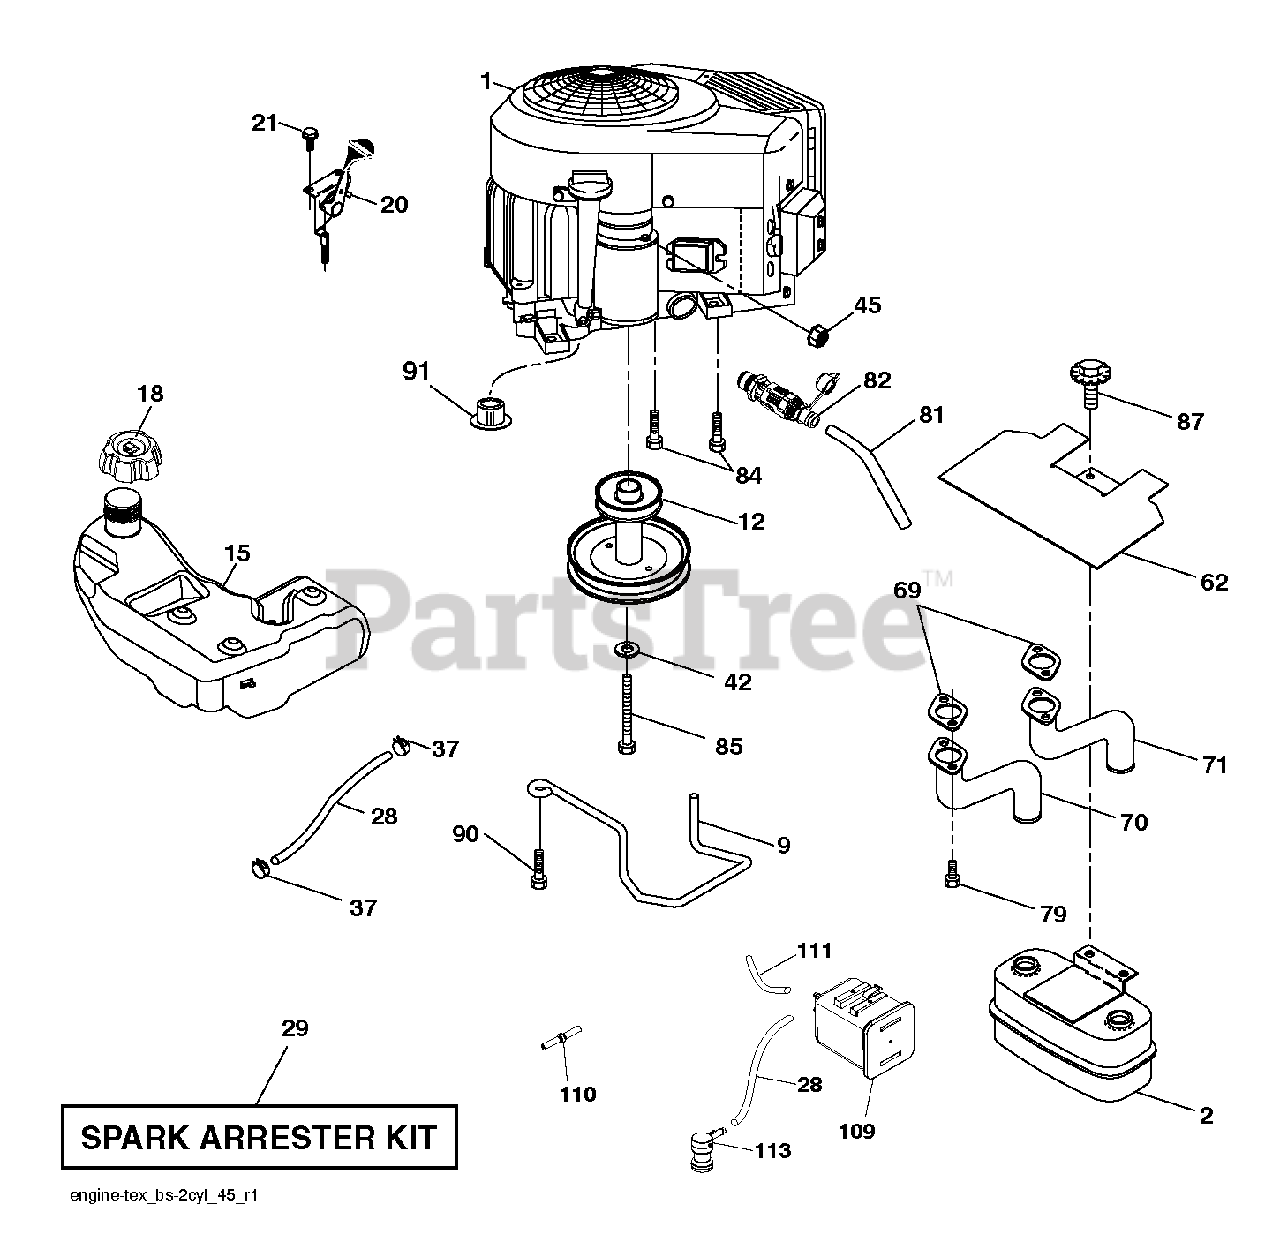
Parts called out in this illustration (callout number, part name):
2	MUFFLER.ASM.TWN.EXTNDED.DFLCTR
9	KEEPER BELT ENGINE
12	PULLY ENGINE
15	TANK ASM.FUEL.3
18	CAP.ASM.FL.RITCH.3"E10.SYM.498
20	CONTROL.TH/CK.COBRA.B&S.TWN.
21	SCREW.#10 X 0.750.BOS
28	LINE.FUEL.64"REAR.EMIS
29	KIT.SPARK ARRESTOR 794945 B&S
37	HOSE CLAMP
42	LOCKWASHER
45	NUT
62	SHIELD.HEAT.MUFFLER
69	GASKET.MUFFLER
70	EXHAUST.TUBE.LH.BS/TWIN
71	EXHAUST.TUBE.RH.B&S.TWIN.INTEK
79	SCREW.SOCKET.HEAD.5/16-18
81	TUBE, DRAIN OIL ASM.
82	VALUE.OIL.DRAIN
84	SCREW.3/8-16
85	BOLT HEX 7/16-20X4-1/4"
87	BOLT, 5/16-18 X 1 3/4
90	SCREW 3/8-16X1
91	BUSHING.1.375OD
109	CANNISTER, CARBON
110	VALVE.ASM.ANTI-SLOSH
111	RP PURGE LINE
113	VALVE.SLANT.CARTRDG.90 DEG.TEX
